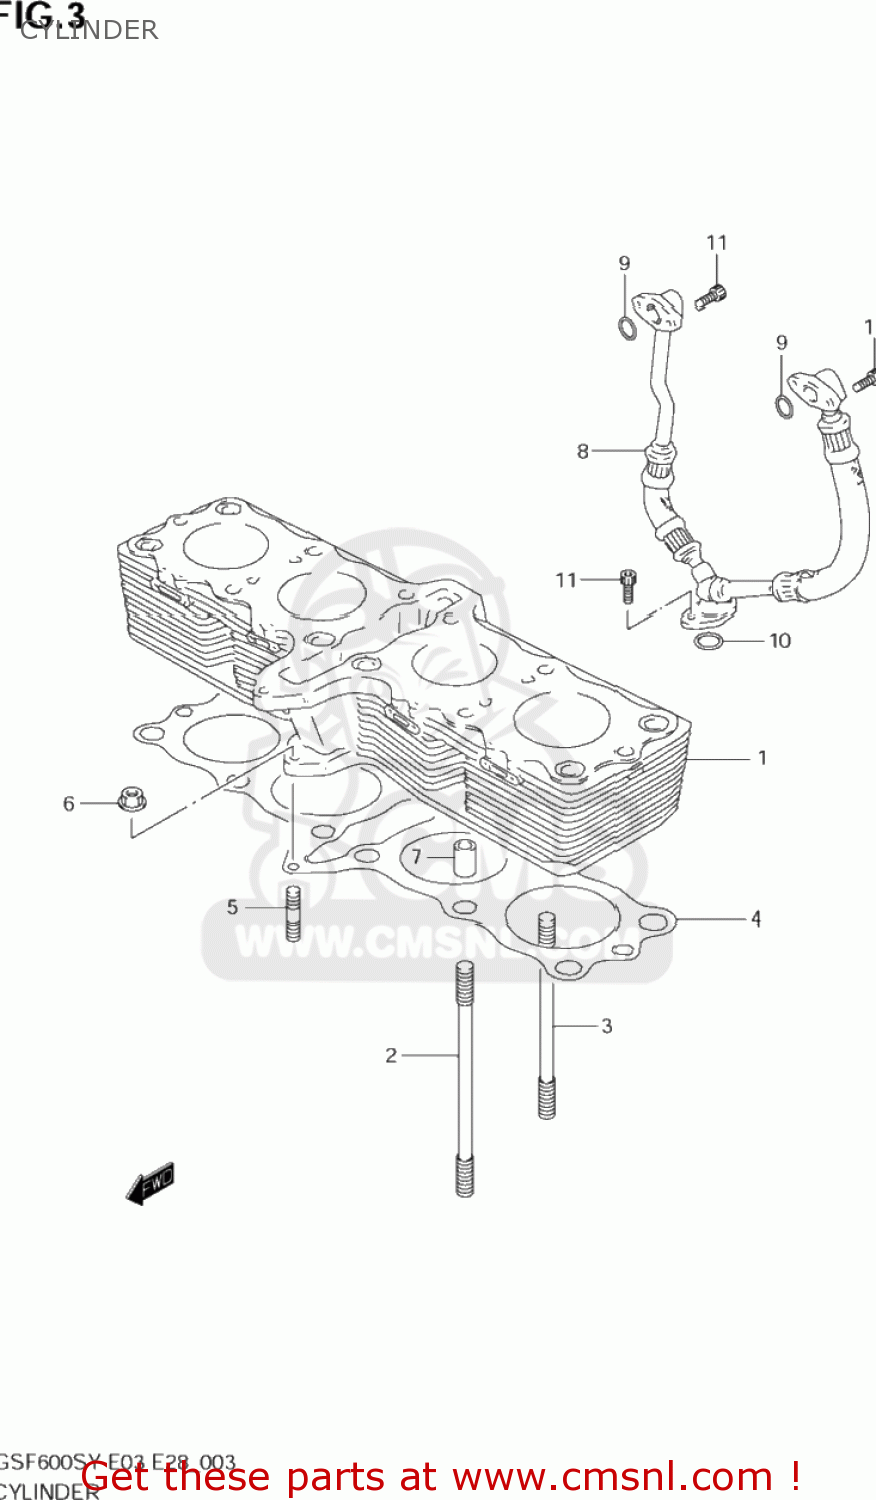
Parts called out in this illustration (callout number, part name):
1	CYLINDER
2	STUD BOLT (L:150)
3	BOLT,STUD
4	GASKET,CYLINDER (NAS)
5	STUD,M6X1X32
6	NUT
7	PIN(13X10.4X20)
8	HOSE,OIL HEAD COOLER
9	O RING(D:2.5,ID:13.8)
10	O RING(D:2.4,ID:15.8)
11	BOLT,OIL FILLE
